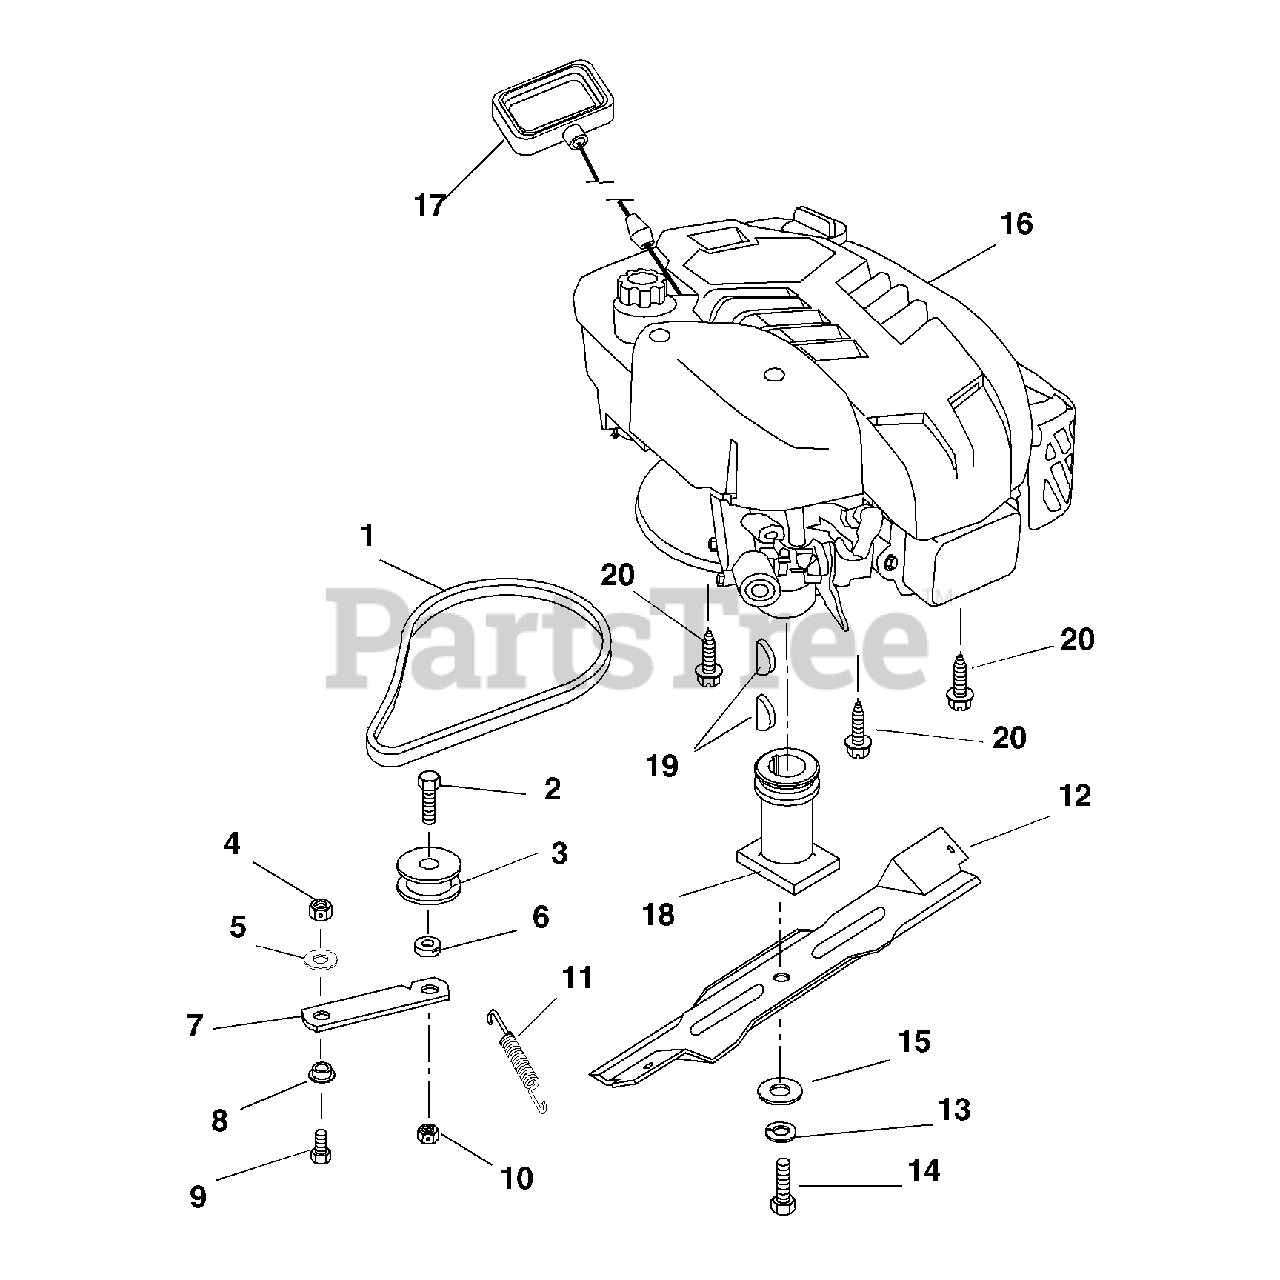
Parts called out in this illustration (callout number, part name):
1	V-BELT, 3L-COGGED
2	@BLT-HEX .44-14X1.25 GR5 YWZC
3	IDLER-FLAT 1.75 X .47
4	@NUT-LK-CTR .31-18 YWZC
5	WSHR-FL-STL .323X.625X.062 YWZ
6	SPACER .52 X .45 X .34
7	IDLER ARM
8	BSHG-FLG .325X.501X.250X1.120
9	@BLT-HEX .31-18X.75 GR5 YWZC
10	@NUT-LK-CTR .44-14 YWZC
11	SG-TENS .043X.44X3.31 WLD 5.8
12	BLADE LM 21 IN
13	@WSHR-LK .38X.094 REG YWZC
14	BLT-HEX .38-24 X 2.00 GR8 YWZC
15	WSHR-FL-STL .390X1.5X.125 YWZC
16	ENGINE, B&S 6.75HP INTEK SCOTT
17	HANDLE, RECOIL START
18	ADAPTER, BLADE
19	KEY-WDRF .156X.625X.25 SAE 6
20	@SCR-TAP .38-16X1.00 HWH TR YZ
